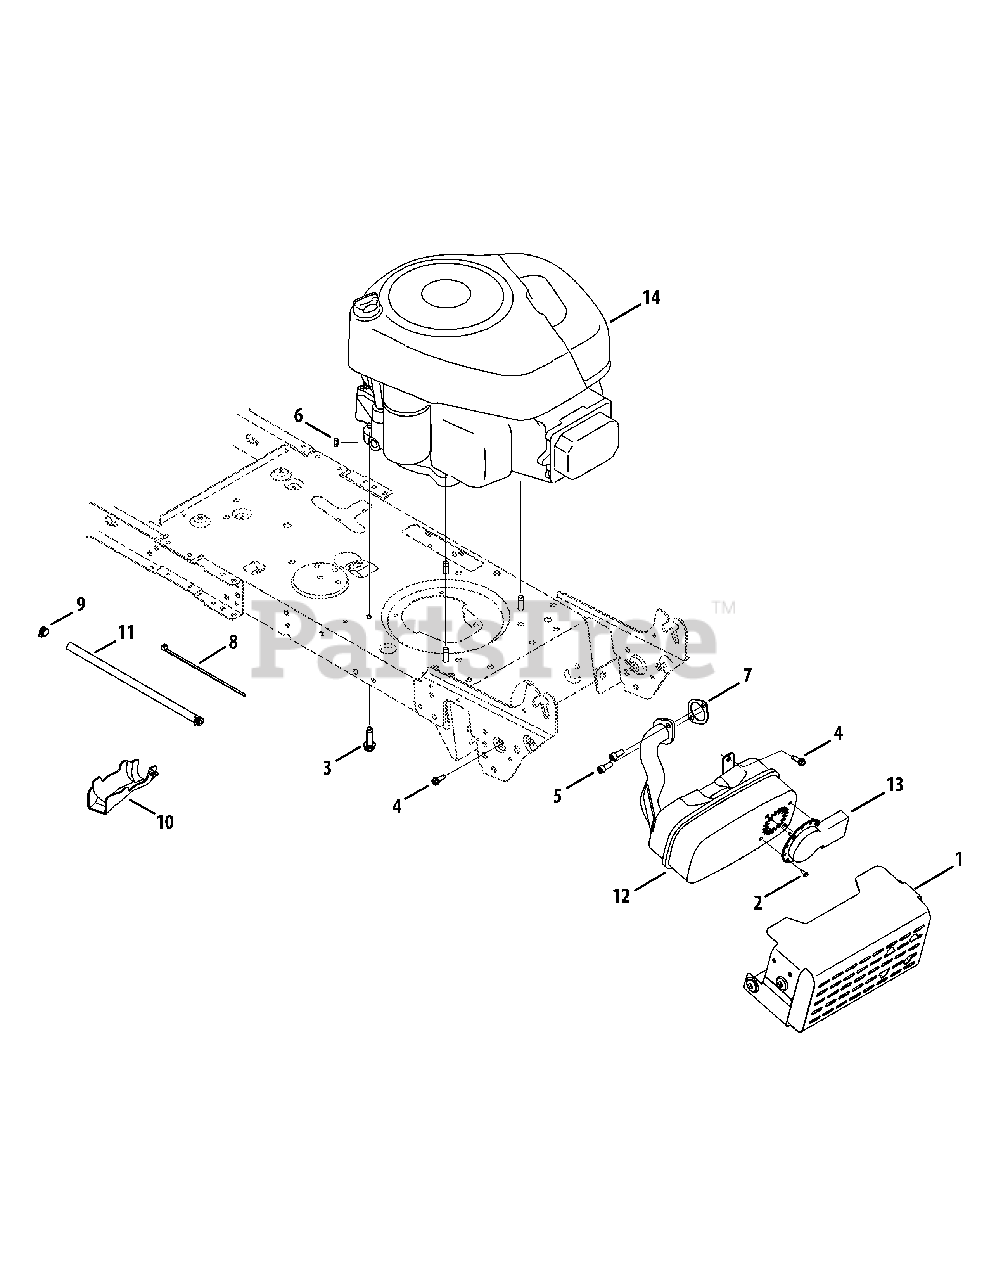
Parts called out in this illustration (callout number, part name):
1	Muffler Shield Assembly
2	Screw, AB #8-18 0.500
3	Tap Screw, 3/8-16 1.000
4	Tap Screw, 1/4-20 0.750
5	Screw, Socket Head, 5/16-18 x .750
6	Sems Nut, 1/4-20
7	Exhaust Gasket
8	Cable Tie, 3/16 X .05 X 7.4
9	Hose Clamp, .490 Dia.
10	Oil Drain Sleeve
11	Low Permeation Fuel Hose, 1/4
12	Briggs Single Muffler
13	Long Muffler Deflector
14	Engine - 31C707-3346-G6
